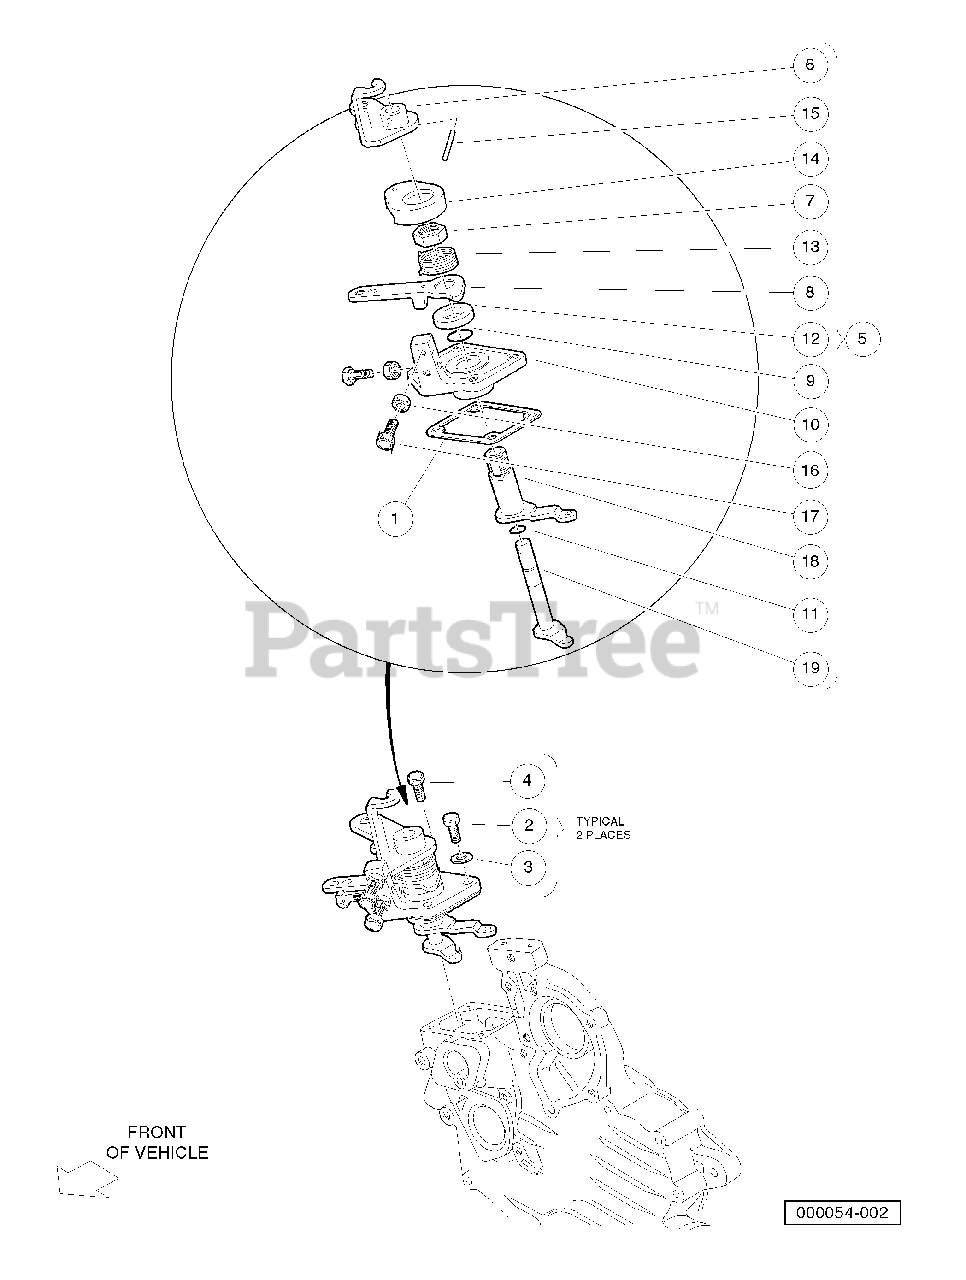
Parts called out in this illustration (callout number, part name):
1	Gasket, Control Plate
2	Bolt, M6 X 1 X 30
3	Gasket, 6 X 10
4	Bolt, D722 Intake Manfld Lower
5	Assembly, Speed Plate
6	Lever, Engine Stop
7	Nut, Speed Control
8	Lever, Speed Control
9	O Ring, 19 X 16
10	Plate, Speed Control
11	O Ring, 9 X 7
12	Collar, Lever
13	Spring, Return
14	Cap, Speed Cntrl Plate Rtrn
15	Pin, Spring, Speed Plate
16	Nut, Speed Control
17	Bolt, Speed Control
18	Lever, Governor
19	Shaft, Governor Lever
